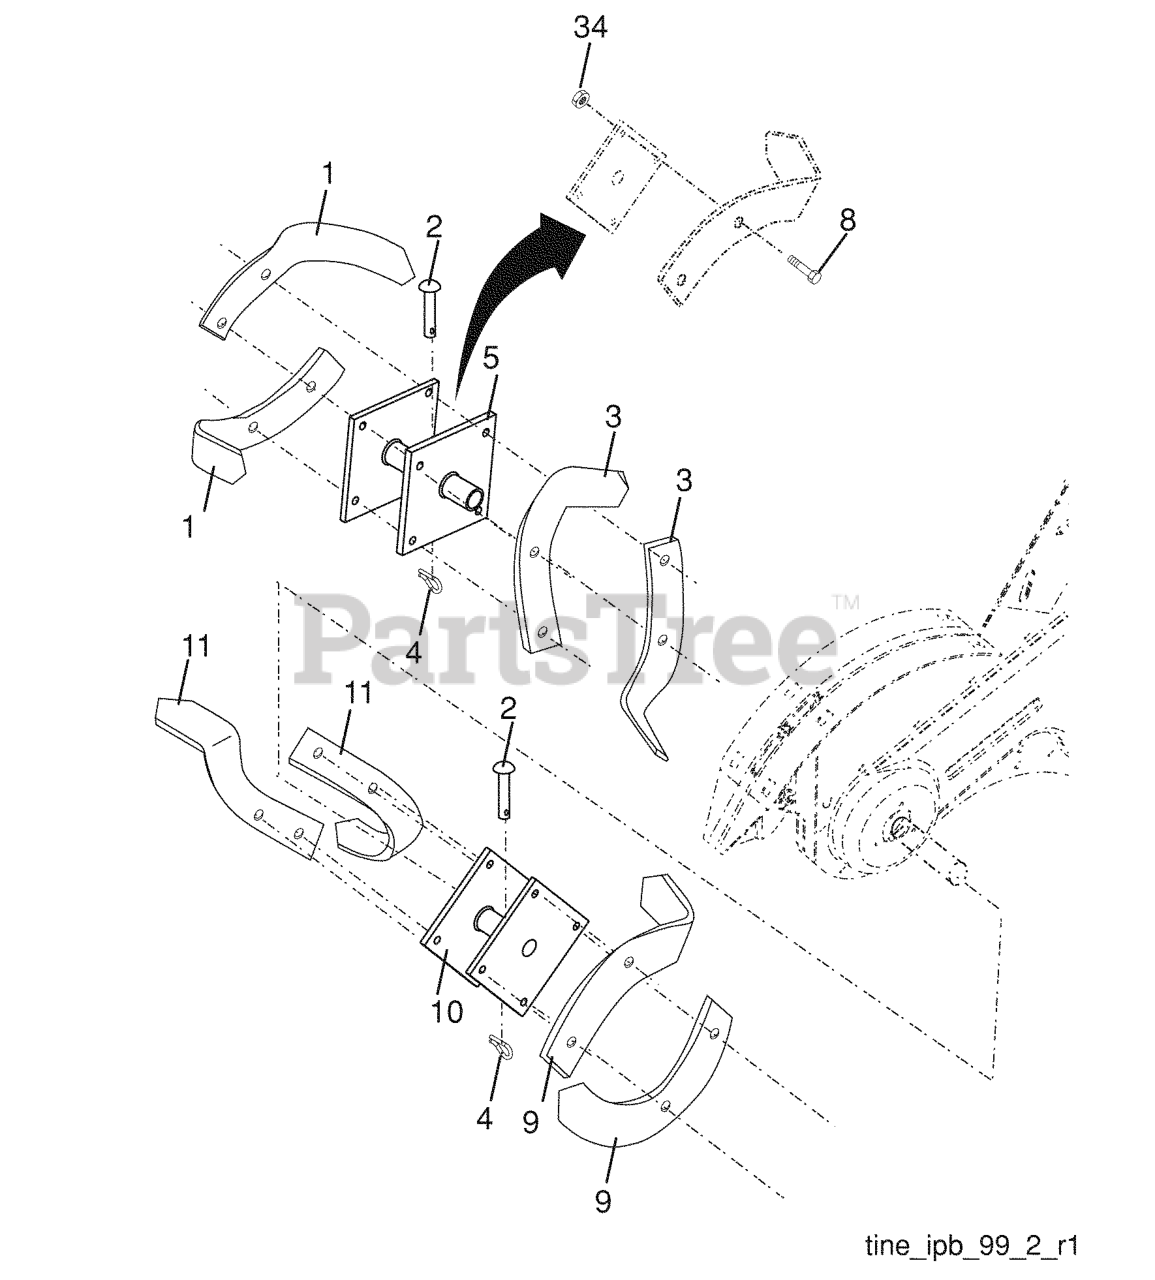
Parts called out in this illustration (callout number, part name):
1	TINE TI
2	PIN RETAINING SCREW
3	TINE.LH.12"(72L)
4	SPRING RETAINER
5	HUB.&.PLATE.LH.TILLER.BLACK
8	BOLT.HEX.001X20.37-24X1.ZINC
9	TINE TI
10	HUB.ASM.RH.14".BLACK.TILLER
11	TINE.RH.12"(72R)
34	NUT CROWNLOCK 3/8-24
